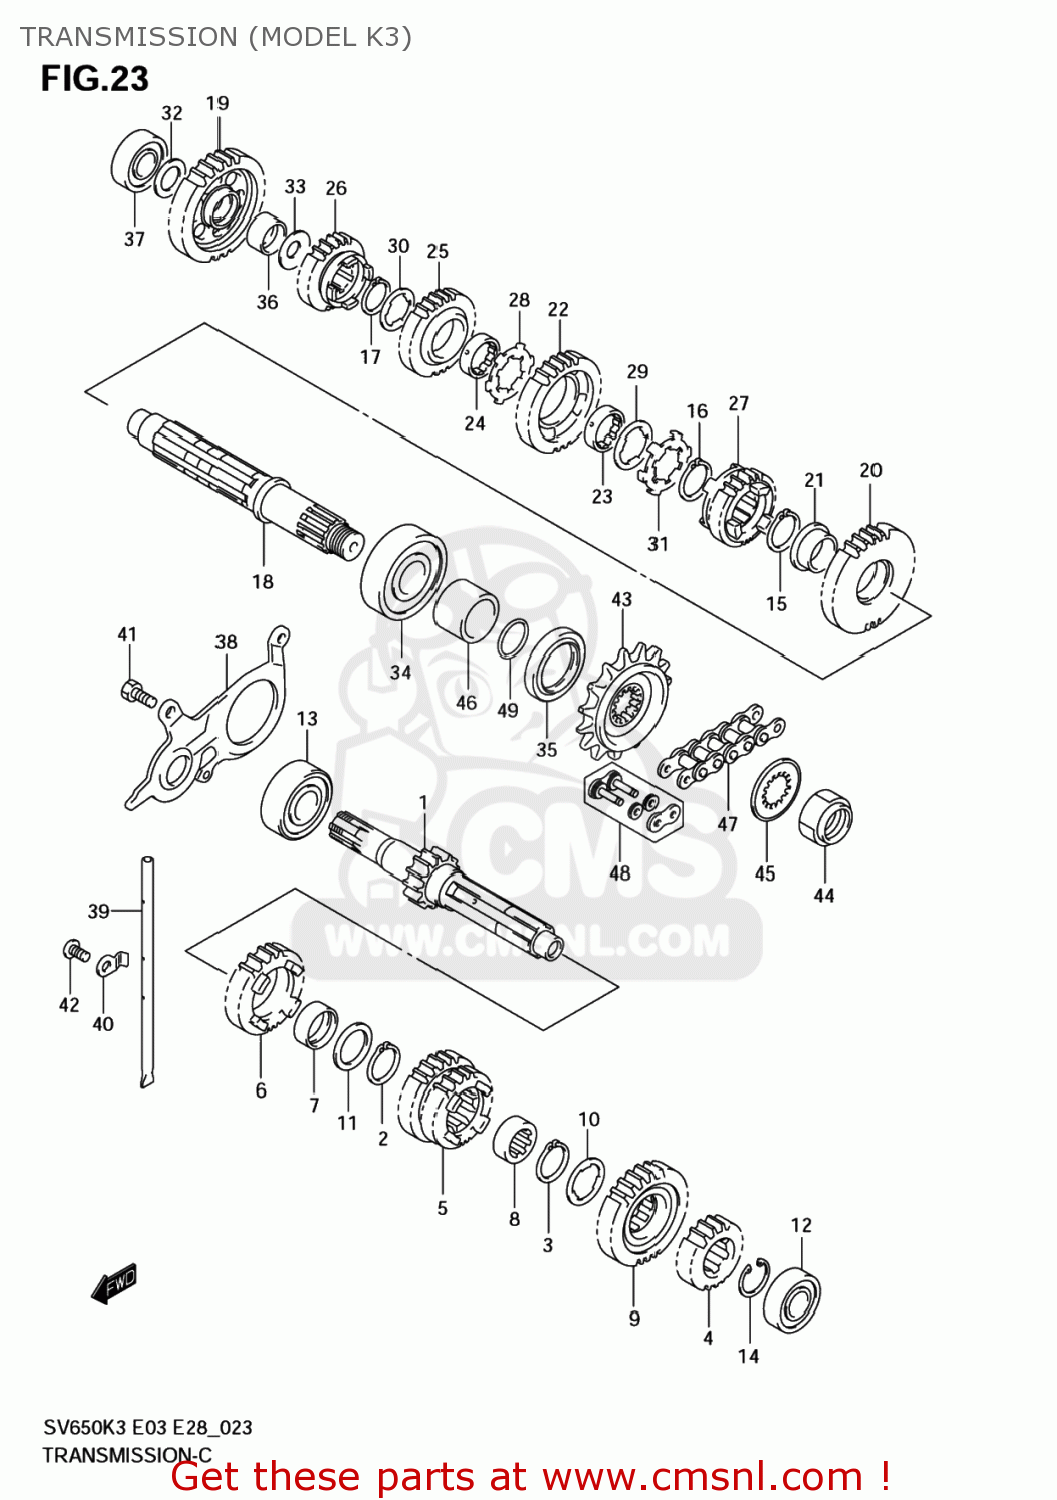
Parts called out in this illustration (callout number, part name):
1	SHAFT,COUNTER(NT:13)
2	CIRCLIP
3	CIRCLIP
4	GEAR,SECOND DRIVE (NT:18)
5	GEAR,3RD & 4TH
6	GEAR,FIFTH DRIVE (NT:26)
7	BUSH
8	BUSH,6TH DRIVE GEAR
9	GEAR,6TH DRIVE(NT:27)
10	WASHER,LOCK
11	SHIM(25X34X1)
12	BEARING(17X40X12)
13	BEARING 20X52X15
14	CIRCLIP
15	CIRCLIP
16	CIRCLIP
17	CIRCLIP
18	SHAFT,DRIVE
19	GEAR,1ST DRIVEN(NT:32)
20	GEAR,SECOND DRIVEN (NT:32)
21	BUSH
22	GEAR,3RD DRIVEN(NT:29)
23	BUSH,DRIVEN GEAR
24	BUSH,DRIVEN GEAR
25	GEAR,4TH DRIVEN(NT:27)
26	GEAR,FIFTH DRIVEN (NT:25)
27	GEAR,SIXTH DRIVEN (NT:23)
28	WASHER,LOCK
29	WASHER,LOCK
30	WASHER,LOCK
31	WASHER
32	SHIM(17X28X1)
33	SHIM(20X30X1)
34	BEARING(25X62X17)
35	SEAL,OIL(36X50X6)
36	BUSH(20X24X13)
37	BEARING(17X40X12)
38	RETAINER,DRIVESHAFT O
39	GUIDE,T/M OIL
40	RETAINER,TRANSMISSION OIL
41	BOLT
42	SCREW
43	SPROCKET,ENGINE(NT:15)
44	NUT
45	WASHER,LOCK
46	SPACER,ENGINE SPROCKET
47	CHAIN,DRIVE(DID525V9,110L)
48	JOINT SET,CHAIN
49	O RING(D:2.4,ID:23.7)
